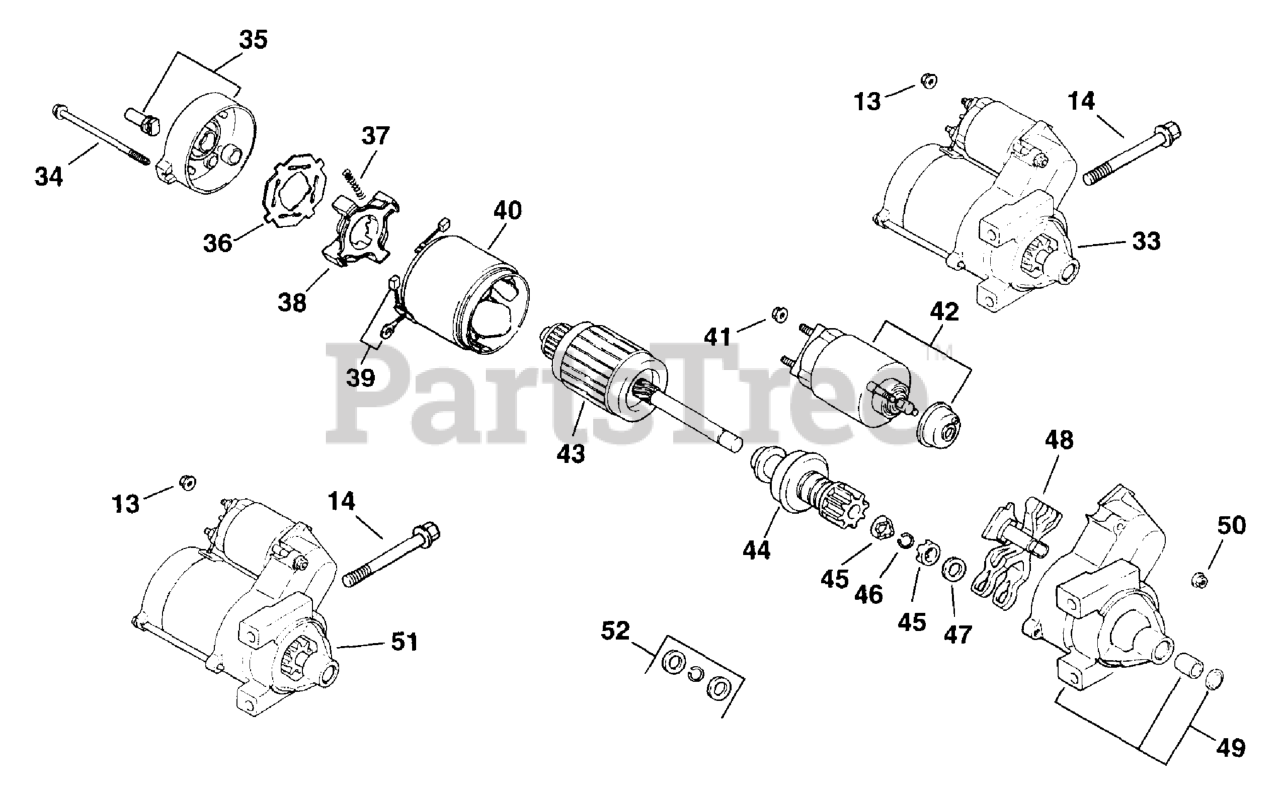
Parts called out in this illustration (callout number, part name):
13	NUT - USE M-841080
14	Screw, hex. flange M8x1.25x80.6
34	THRU BOLT
35	COMMUTATOR, END CAP - DISCONTINUED
36	INSULATOR
37	SPRING, BRUSH
38	BRUSH HOLDER
39	BRUSH & SPRING KIT
40	FRAME W/BRUSHES - DISCONTINUED
43	ARMATURE - DISCONTINUED
44	DRIVE PINION
45	KIT - USE 24 755 84
46	KIT - USE 24 755 84
47	KIT - USE 24 755 84
48	LEVER, DRIVE
49	DRIVE, END CAP
52	Kit, starter repair
